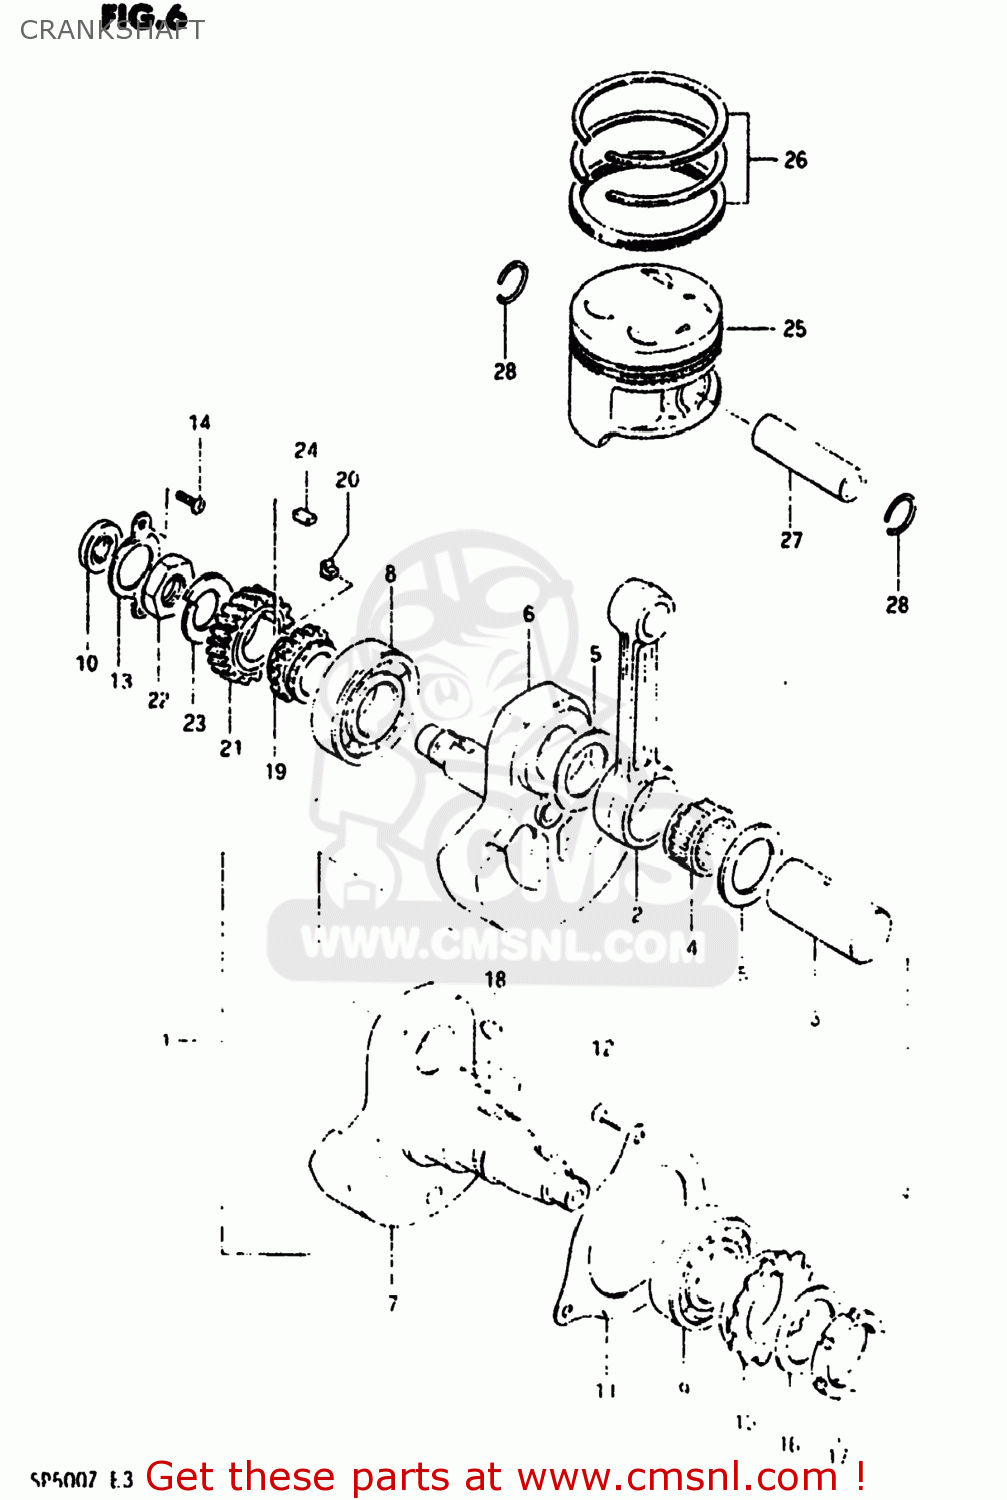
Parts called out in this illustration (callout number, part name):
1	CRANKSHAFT ASSEMBLY
2	ROD,CONNECTING
3	PIN,CRANK
4	BEARING(35X44X26)
5	WASHER(35X55X1)
6	CRANKSHAFT
7	CRANKSHAFT,LEFT
8	BEARING(35X80X21)
9	BEARING
10	SEAL,OIL(16X30X6)
11	RETAINER,CRANKSHAFT BEARING,L
12	SCREW
13	RETAINER,CRANKSHAFT BEARING,R
14	SCREW
15	SPROCKET,BALANCER DRIVE
16	WASHER
17	NUT,FLYWHEEL
18	KEY
19	SPROCKET,CAM CHAIN DRIVE
20	KEY,SPROCKET
21	GEAR,PRIMARY DRIVE
22	NUT (20MM)
23	WASHER
24	KEY
25	PISTON
26	RING SET,PISTON
27	PISTON PIN
28	RING,SNAP
